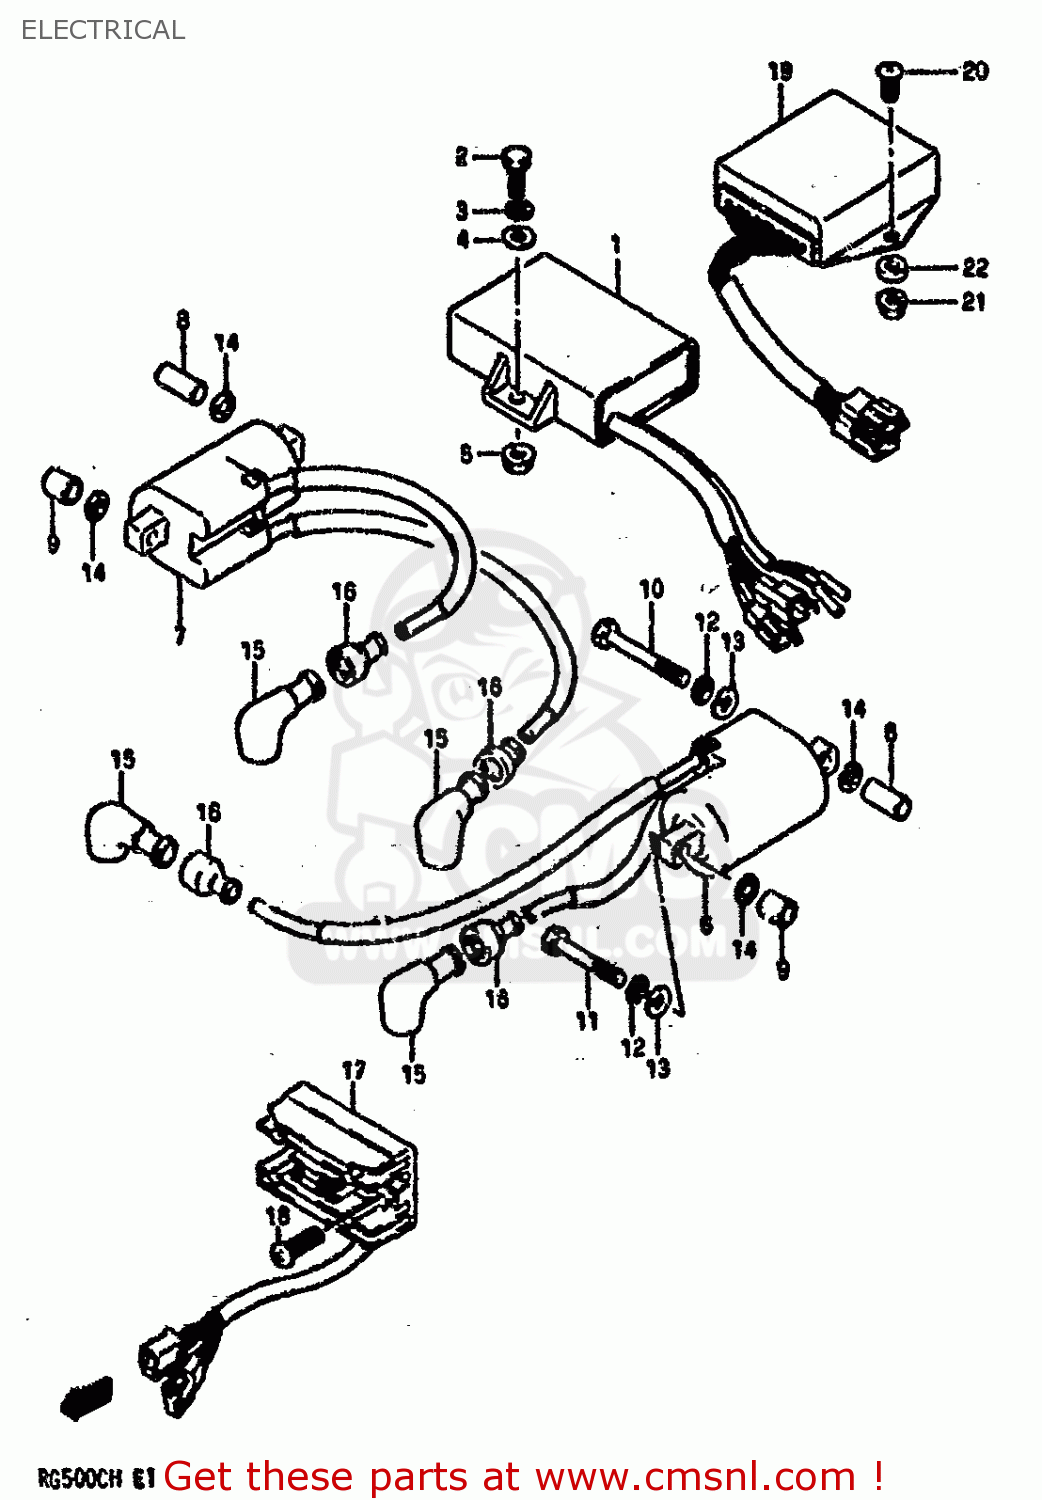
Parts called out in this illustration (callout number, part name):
1	CDI UNIT
2	BOLT,M6X1X20
3	WASHER,LOCK
4	WASHER, LOWER
5	NUT
6	COIL ASSY,IGN.
7	COIL ASSY,IGN.
8	SPACER (6.8X10X20)
9	SPACER
10	BOLT 6X50
11	BOLT
12	WASHER,LOCK
13	WASHER, LOWER
14	WASHER(6.5X16X1.2)
15	CAP,SPARK PLUG
16	SEAL,SPARK PLU
17	RECTIFIER
18	SCREW
19	EXHAUST CTRL
20	SCREW
21	NUT
22	WASHER
